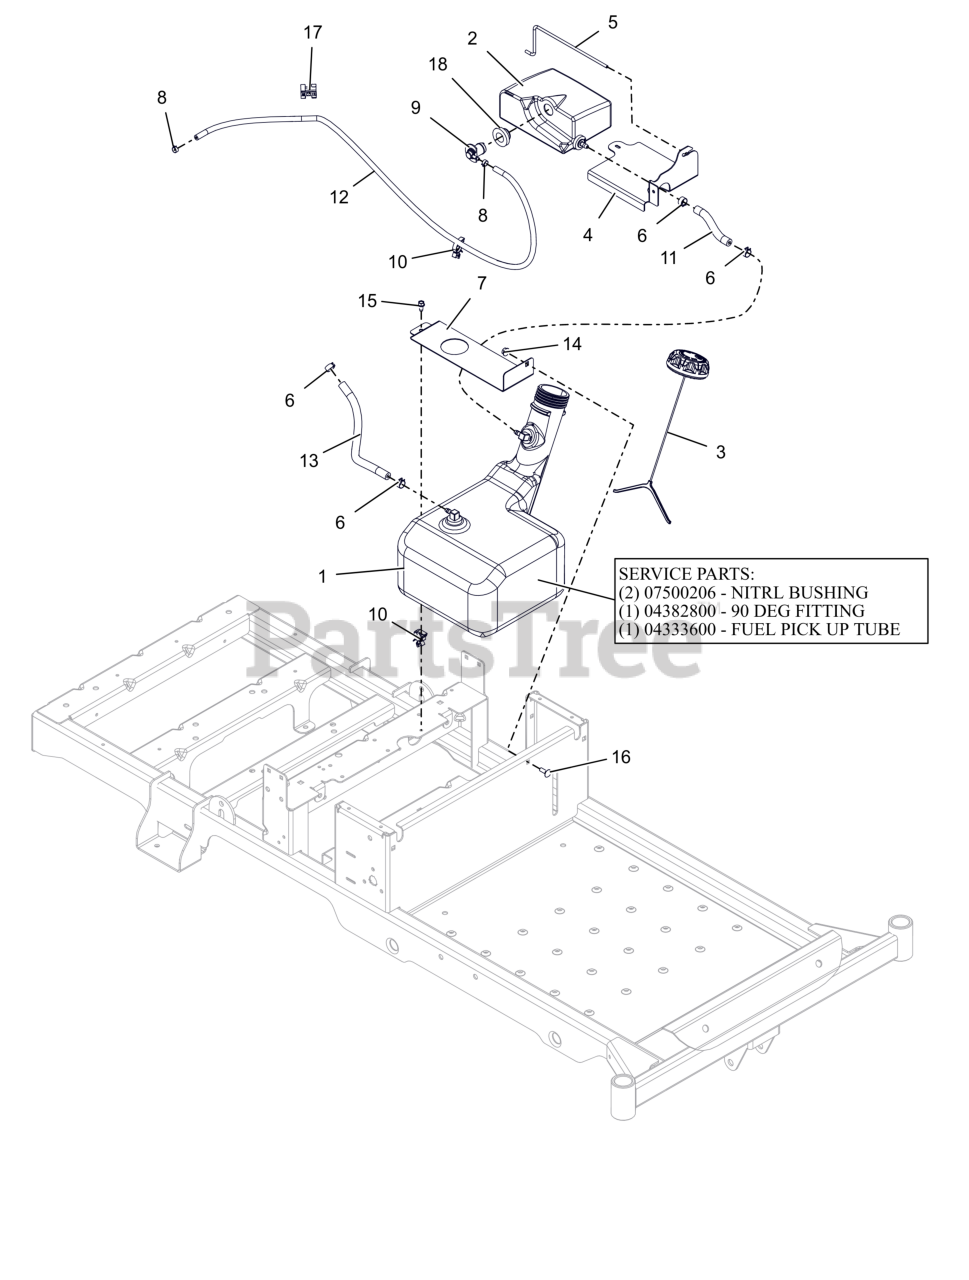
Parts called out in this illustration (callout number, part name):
1	ASM, FUEL TANK-ZOOM
1	BSHG-FLG .375X1.062X.625 NITR
1	FITTING, 90 DEG FUEL-PLASTIC
1	FUEL PICK UP TUBE
2	ASM, FUEL TANK - EXPANSION
3	CAP, FUEL VENT-IN 2.25" RATCH.
4	BRKT, EXPANSION TANK (ORANGE)
5	ROD, HOLDDOWN (BLACK)
6	CLAMP, FUEL LINE
7	BRKT, TANK STRAP
8	CLAMP-HOSE, SPRING .188
9	VALVE, 2-WAY
10	WIRE CLIP
11	HOSE, .25 LOW-PERM BULK GAS
12	HOSE, .188 LOW-PERM BULK GAS
13	HOSE, .25 LOW-PERM BULK GAS
14	NUT-LK-CTR-FLG .25-20 ZC120
15	SCR-TAP .25-20X.50 HWH ZCC
16	BLT, RHSN .25-20X.750 G5 ZCC
17	CLIP, T, .38-.50
18	GROMMET, REMOTE VENT NITRILE
